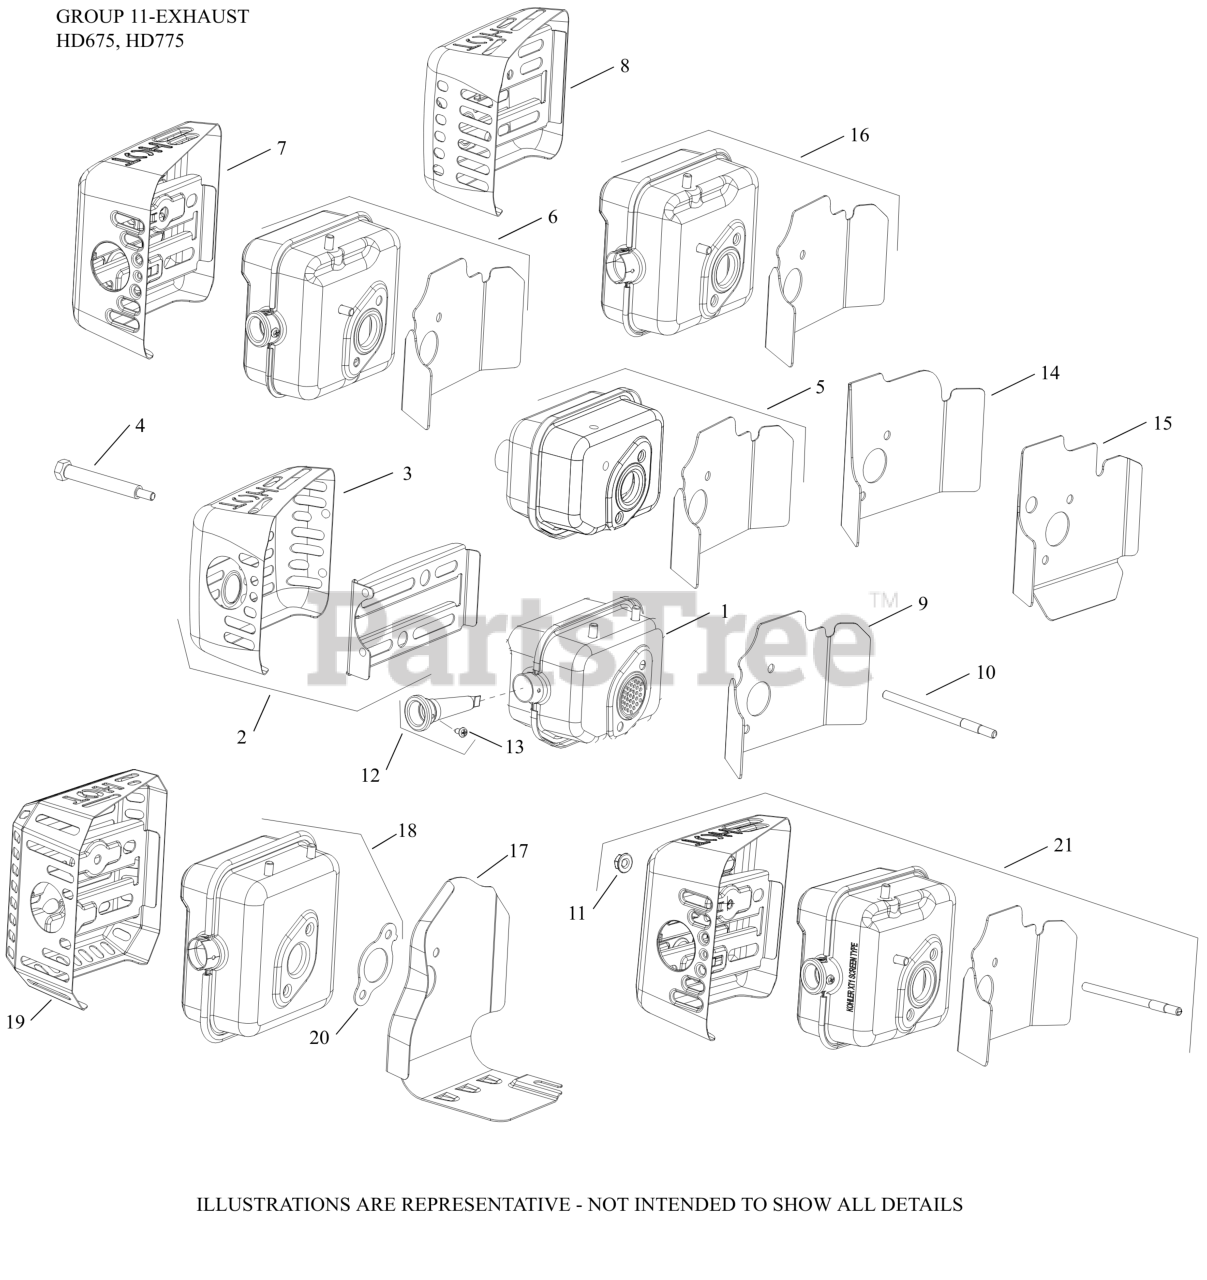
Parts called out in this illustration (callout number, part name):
7	GUARD, MUFFLER ASSEMBLY
9	GASKET, MUFFLER (HEAT DEFLECTOR)
10	STUD, EXHAUST (M6)
11	NUT, HEX FLANGE LOCK (M6)
21	KIT, MUFFLER
